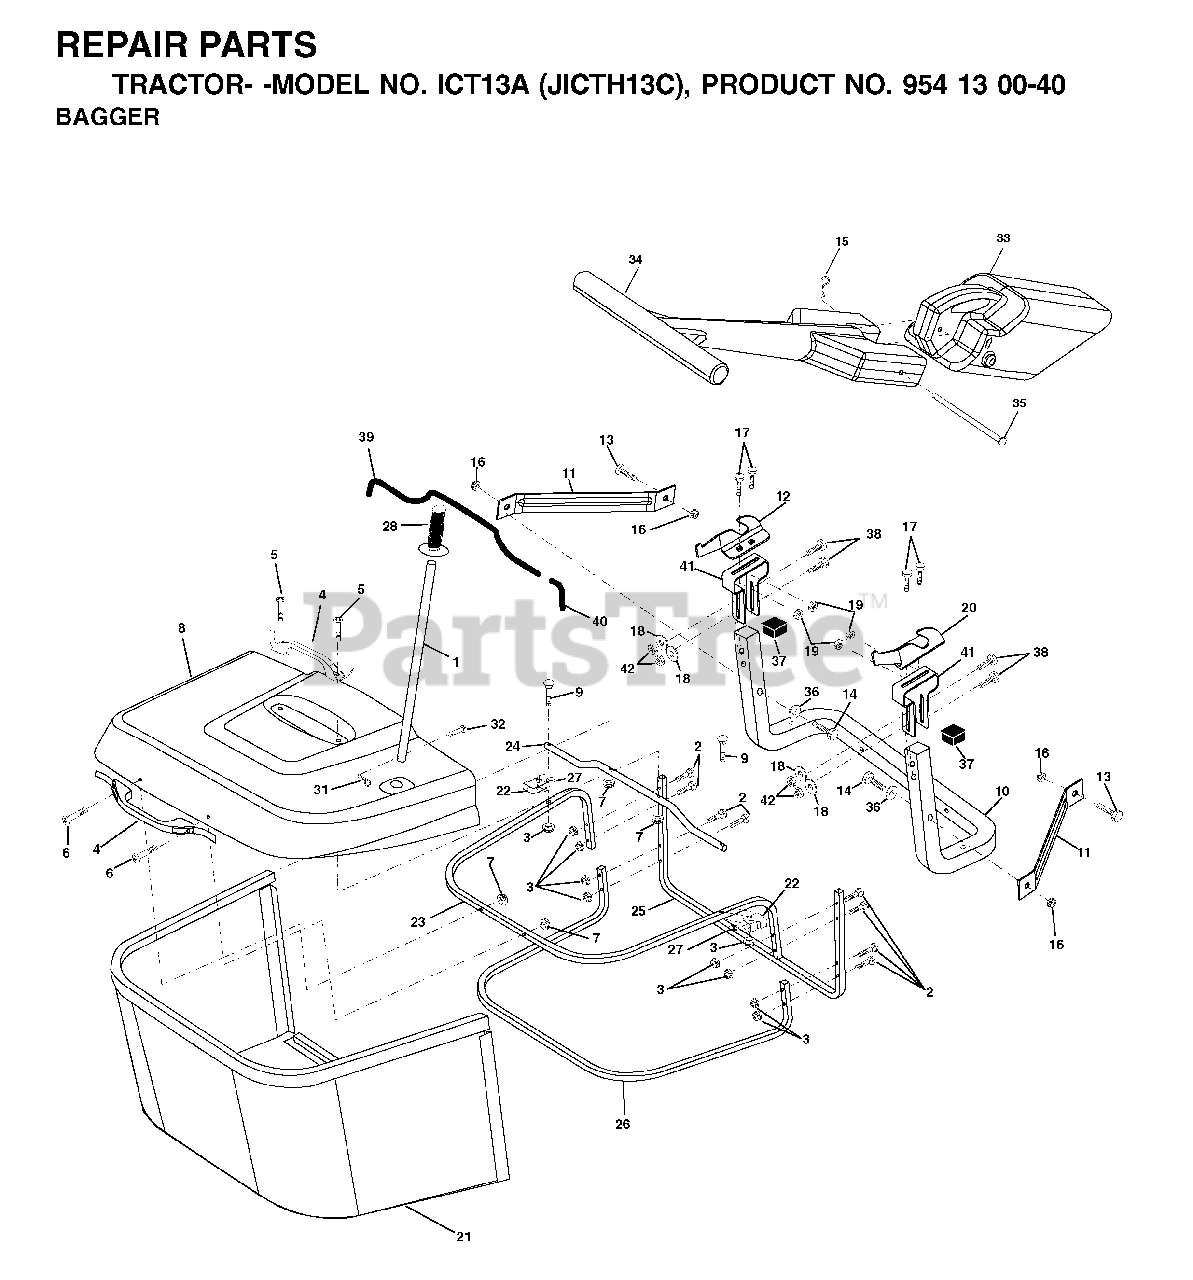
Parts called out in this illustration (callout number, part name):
1	TUBE HANDLE BAGGER
3	NUT T
5	SCREW.PAN.HEAD
10	TUBE
11	BRACKET
15	RETAINER-SPRNG RB
16	NUT LOCK FLG 3/8-16 UNC
17	BOLT
18	WASHER M
19	NUT LOCK HEX FLANGE 5/16-18
20	BRACKET
21	BAG
22	BRACKET
23	TUBE
24	TUBE
26	TUBE
31	RETAINER M
32	RIVET,DRILLED
33	PLUG
35	PIN
36	WASHER
38	BOLT.5/16-18X2.5
39	TRIM
40	TRIM
41	BRKT, BAGGER
42	NUT.71038.31-18.HEX.NYLOCK
